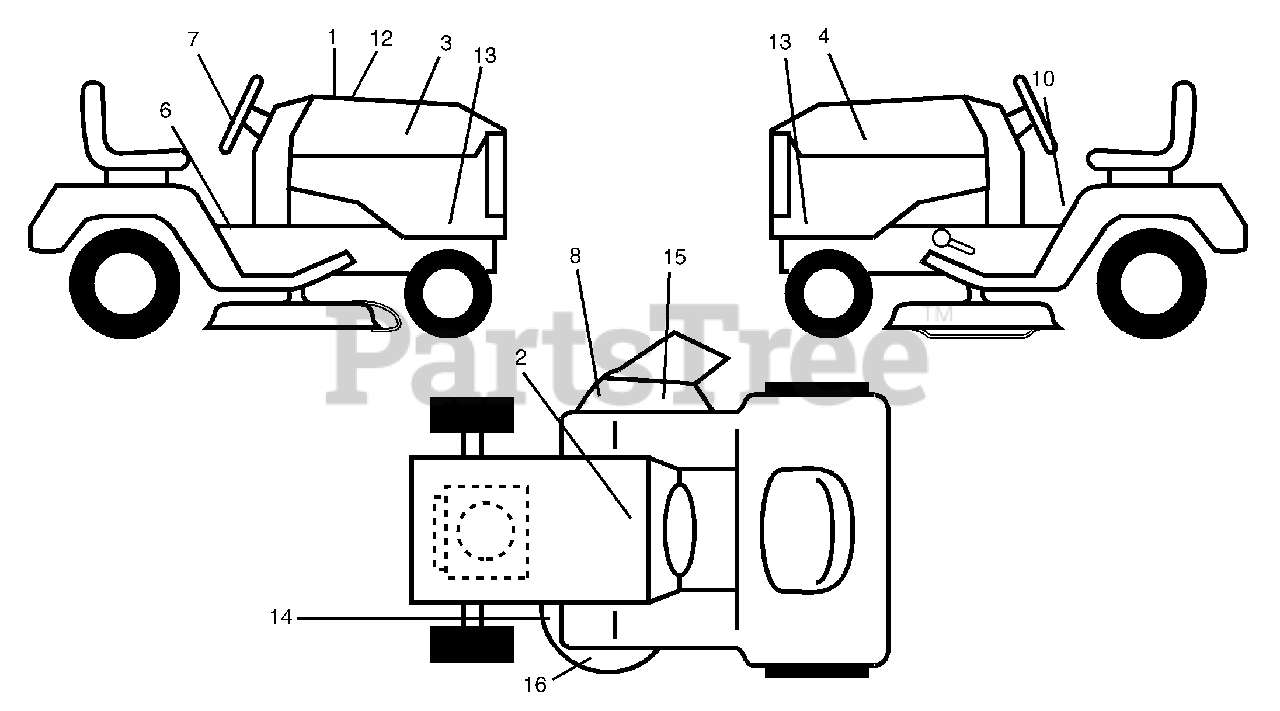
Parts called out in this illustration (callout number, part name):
1	Decal Hood Cust. Resp.
2	Decal Battery
3	Decal Hood RH
4	Decal Hood LH
6	Decal Fender Oper
7	Decal Wheel Steering
8	Decal Warning Keep Hand Away
10	Decal Fender Danger E/F
12	Decal Hood
13	Decal Hoodsides
14	Decal V-Belt Schematic
15	Decal Deck "B" 42"
16	Decal Mower
